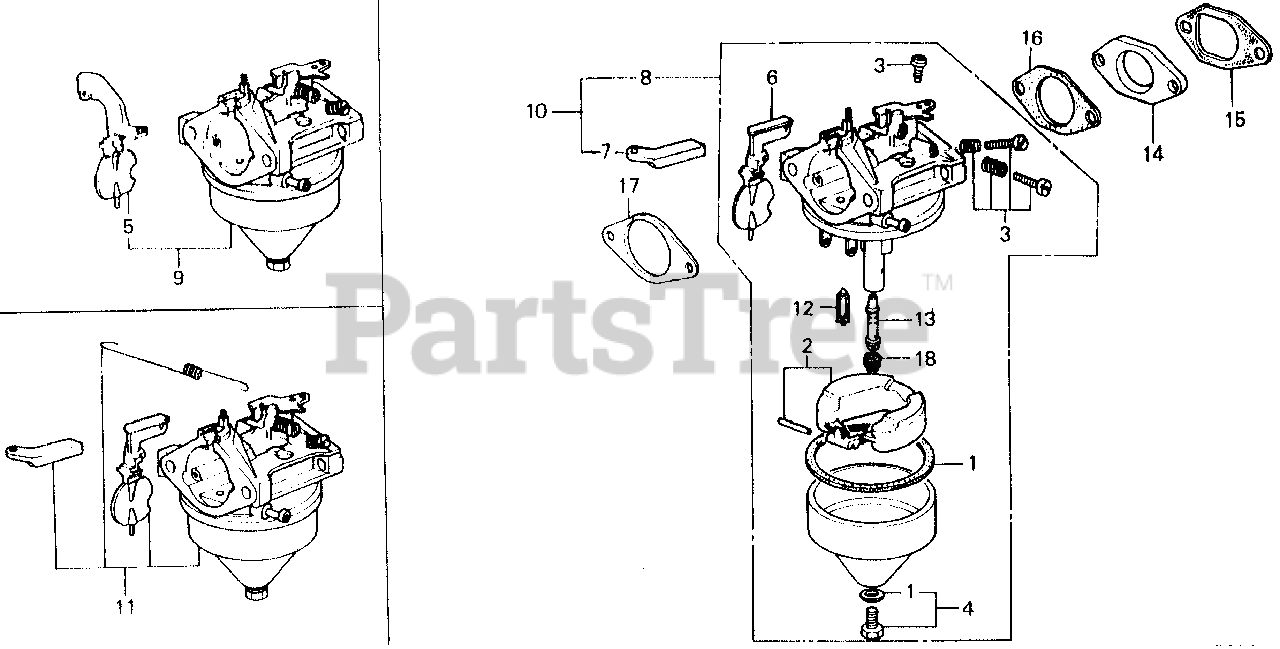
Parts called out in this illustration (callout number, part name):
1	GASKET SET
2	FLOAT SET
3	SCREW SET A
4	SCREW SET B
5	CHOKE SET
6	CHOKE SET
7	ARM, CHOKE LEVER Use from Engine SN 1139504 to 1335195.
8	CARBURETOR ASSY.
9	CARBURETOR ASSY.
10	CARBURETOR ASSY.
11	CARBURETOR ASSY.
12	VALVE, FLOAT
13	NOZZLE, MAIN
14	INSULATOR, CARBURETOR
15	GASKET, INSULATOR
16	GASKET, CARBURETOR
17	GASKET, AIR CLEANER
18	JET, MAIN (#55) Use up to Engine SN BB28A D.
18	JET, MAIN (#58) Use up to Engine SN BB28A D.
18	JET, MAIN (#60) Use up to Engine SN BB28A D.
18	JET, MAIN (#62)
